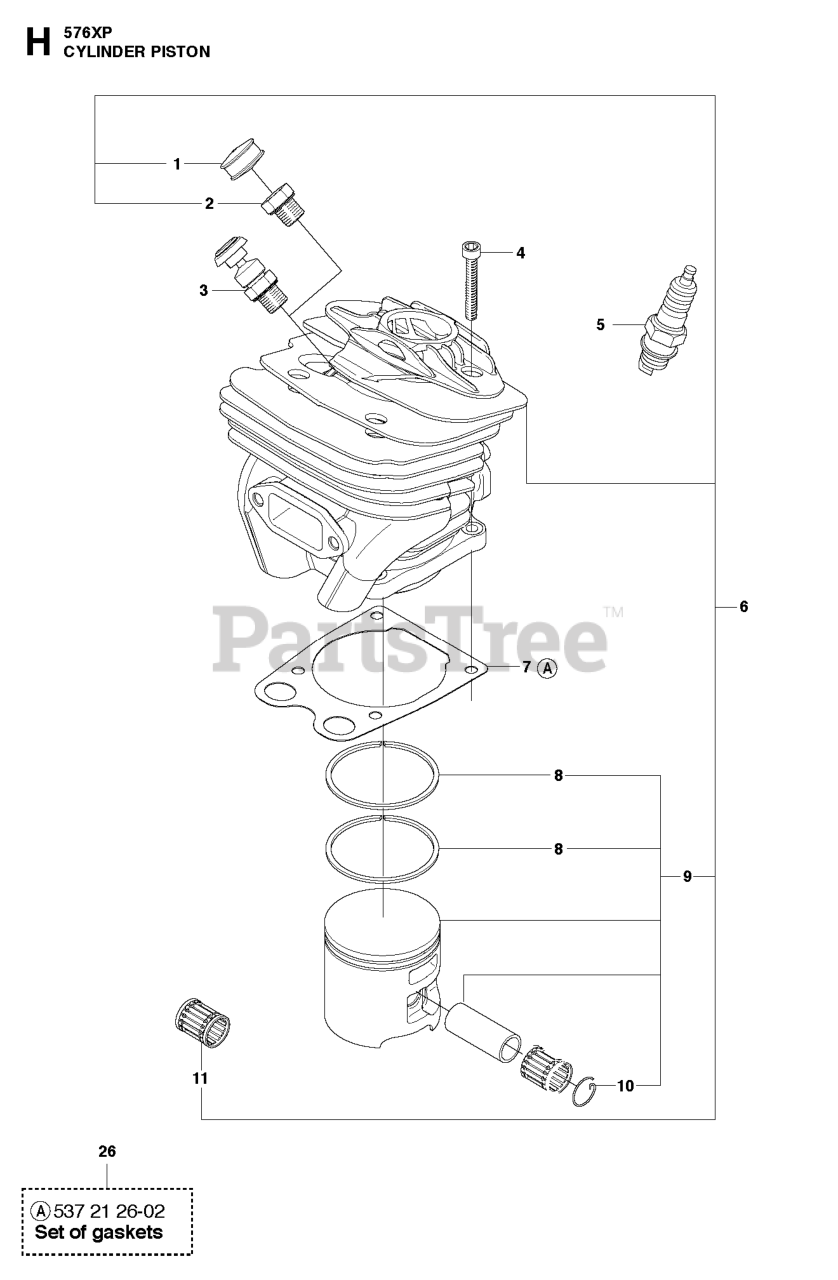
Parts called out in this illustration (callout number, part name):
2	CYLINDER PLUG
4	SCREW MC6S 5X25
5	SPARK PLUG M14X1.25 NGK BPMR7A
6	CYLINDER ASSY
8	PISTON RING
9	PISTON ASSY
10	WRIST PIN CLIP
11	NEEDLE BEARING PISTON PIN 12X1
26	GASKET KIT
